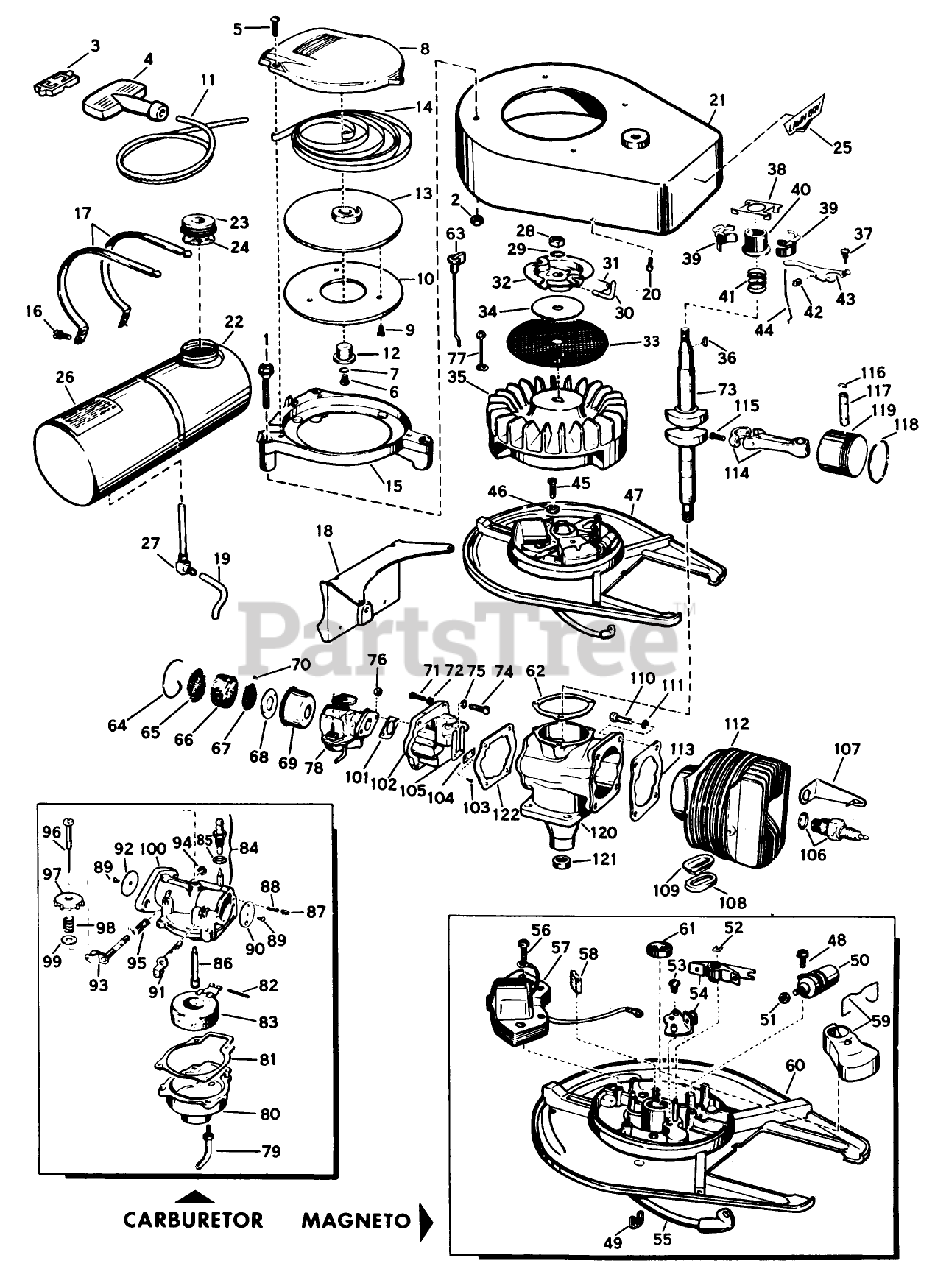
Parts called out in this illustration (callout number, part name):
14	RECOIL SPRING
15	Base-Starter
20	SCREW S
23	Gas Cap
26	Decal-Instruction
30	PIN - STARTER
40	COLLAR S
42	WEAR BLOCK S
43	GOVERNER LEVER AY
44	GOVERNOR ROD S
54	BREAKER AY. S
58	Oiler Wick
62	GASKET S
66	ELEMENT
68	BACK-UP PLATE
71	SCREW S
73	Crankshaft
76	STOP NUT
77	Stop-Choke Link
89	Screw-Choke Disc
95	SPRING
96	NEEDLE AY. S
98	Spring-Ndl. Adj.
101	GASKET S
104	PLATE-BACKUP, REED
106	Spark Plug
112	Cylinder Sleeve Assembly
115	Screw-Connecting Rod
118	Ring-Piston
